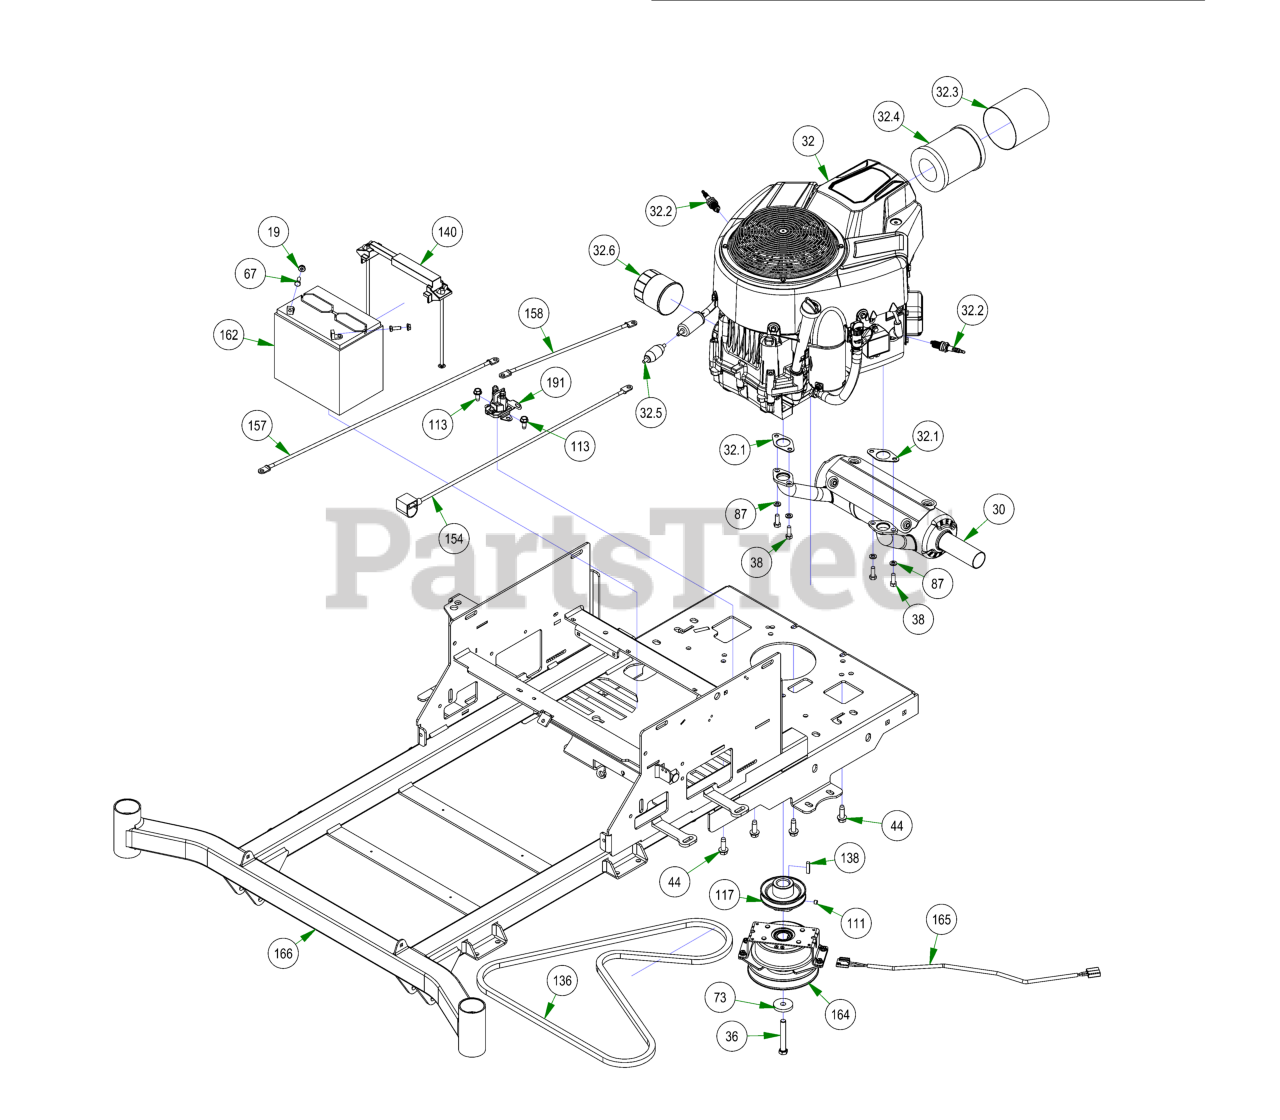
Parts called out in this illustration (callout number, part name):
19	1/4-20 HEX SERRATED FLANGE NUT HARD/ZINC
30	2017 Compact Outlaw Exhaust 810 Vanguard
32	Vanguard 25hp CXI with out Oil Filter 1" Shaft ZT Avenger
32.1	Exhaust Gasket
32.2	Spark Plug
32.3	pre-Cleaner for Vanguard CXI Engine
32.4	Air Filter for Vanguard CXI Engine
32.5	Universal Inline Fuel Filter
32.6	Oil Filter
36	7/16-20x3” Hex Bolt GR 8 W/ Patch
38	Torx Bolt-Exhaust
44	3/8-16 X 1-1/8HEX WASHER UNSLOT SERRATED (TRI-LOB) TRS
67	1/4-20 X 3/4 HEX CAP SCREW (GR.5) ZINC
73	CLUTCH WASHER
87	5/16 SPLIT LOCKWASHER ZINC
111	5/16-24 X 1/4 SOCKET SET SCREW (CUP PT) PLAIN
113	5/16-18 X 3/4HEX WASHER SLOT (F) TCS ZINC
117	3-3/4" Motor Pulley
138	1/4 X 1 SQ MACHINERY KEY 1018 STL PLN
140	Hold Down Assembly
154	24 inch Black Cable – MZ/ZT
157	24" Red Battery Cable
158	12 in red battery cable
162	SP-35 Battery
165	Clutch Pigtail
166	2022 MZ/ZT 54"-60" Frame
